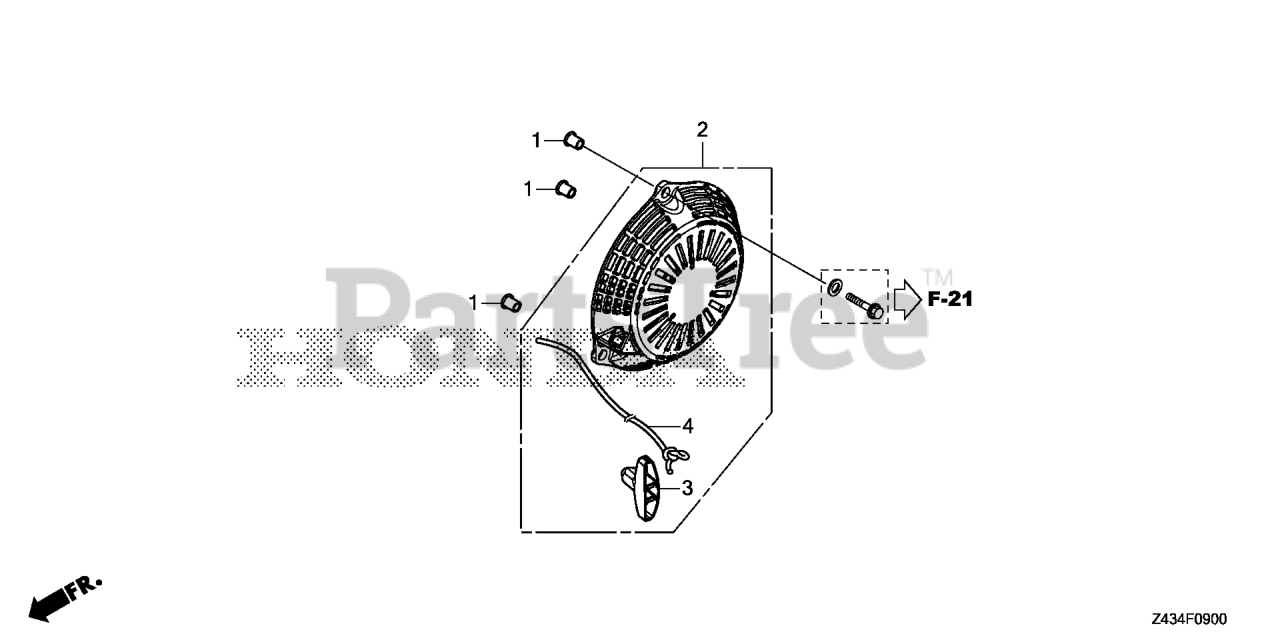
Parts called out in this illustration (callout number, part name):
1	COLLAR, AIR GUIDE
2	STARTER ASSY., RECOIL *NH1* (BLACK)
3	KNOB, RECOIL STARTER
4	ROPE, RECOIL STARTER
